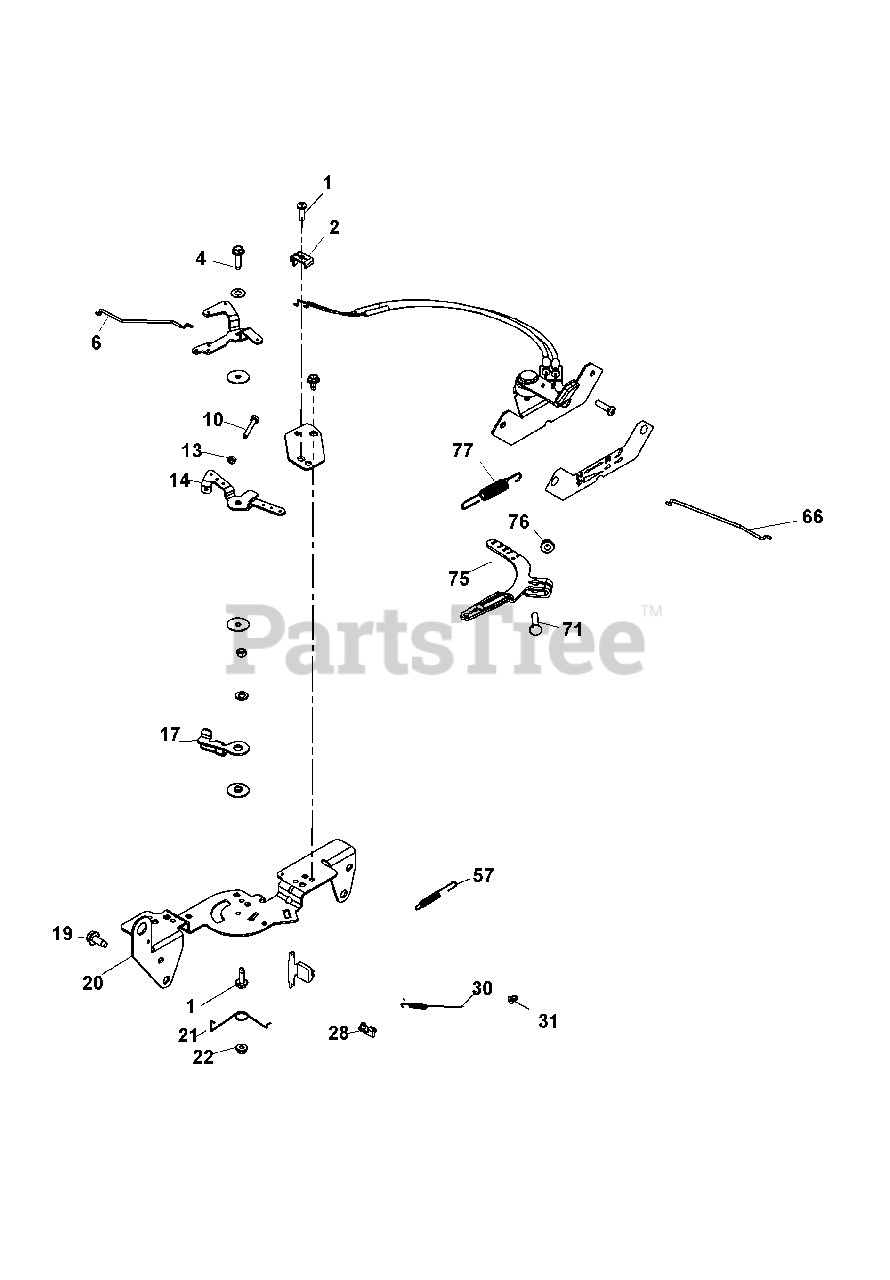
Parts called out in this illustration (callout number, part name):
1	Screw, Thread Forming
2	Clamp, Cable
4	Screw, Thread Forming
6	Linkage, Choke
10	Screw, Cap M4X.7X30
14	Spacer, Control Assy
17	Lever, Throttle Actuator
19	Screw, Thread Forming
20	Bracket, Control
21	Spring, Choke Return
22	Nut, Lock M5X.8
28	Bushing, Throttle Linkage
30	Spring, Linkage
31	Bushing, Linkage Retaining
57	Spring, Throttle Limiter
66	Linkage, Throttle
71	Bolt, Rd Hd Sq Neck M6X1.0X25
75	Lever, Governor
76	Nut, Flg M6X1.0
77	Spring, Governor (Purple)
